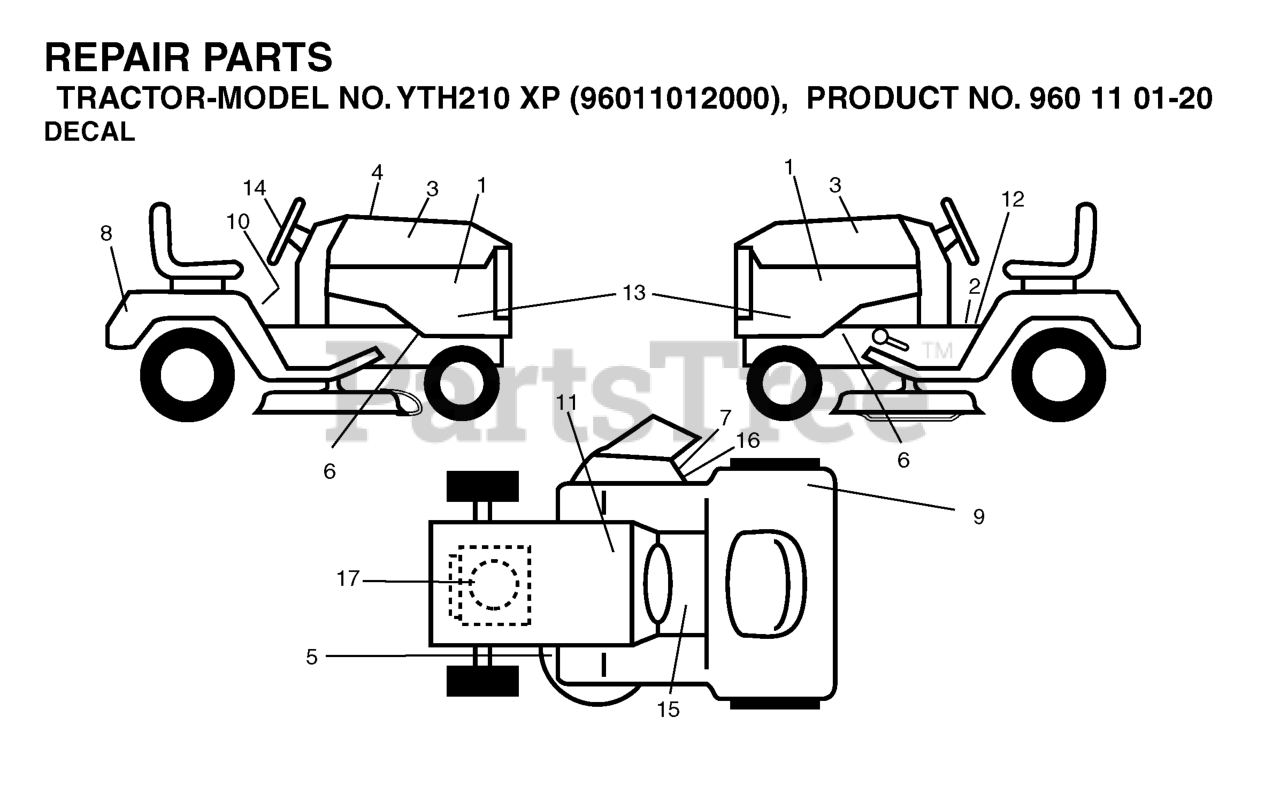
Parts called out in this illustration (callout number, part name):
1	DECAL.HOOD.HUSQVARNA.INTERNATI
2	DECAL PARK BRAKE
5	DECAL V BELT SCHEMATIC
7	DECAL.INTERNATIONL.CUTFINGER
9	Decal, Fender 100 DB/CE
10	LABEL
11	DECAL BTRY SYMBOLS
12	DECAL
14	DECAL.STEERING.HUSQ.BLUE
15	DECAL
16	DECAL, DEFLECT WARNING
17	DECAL
